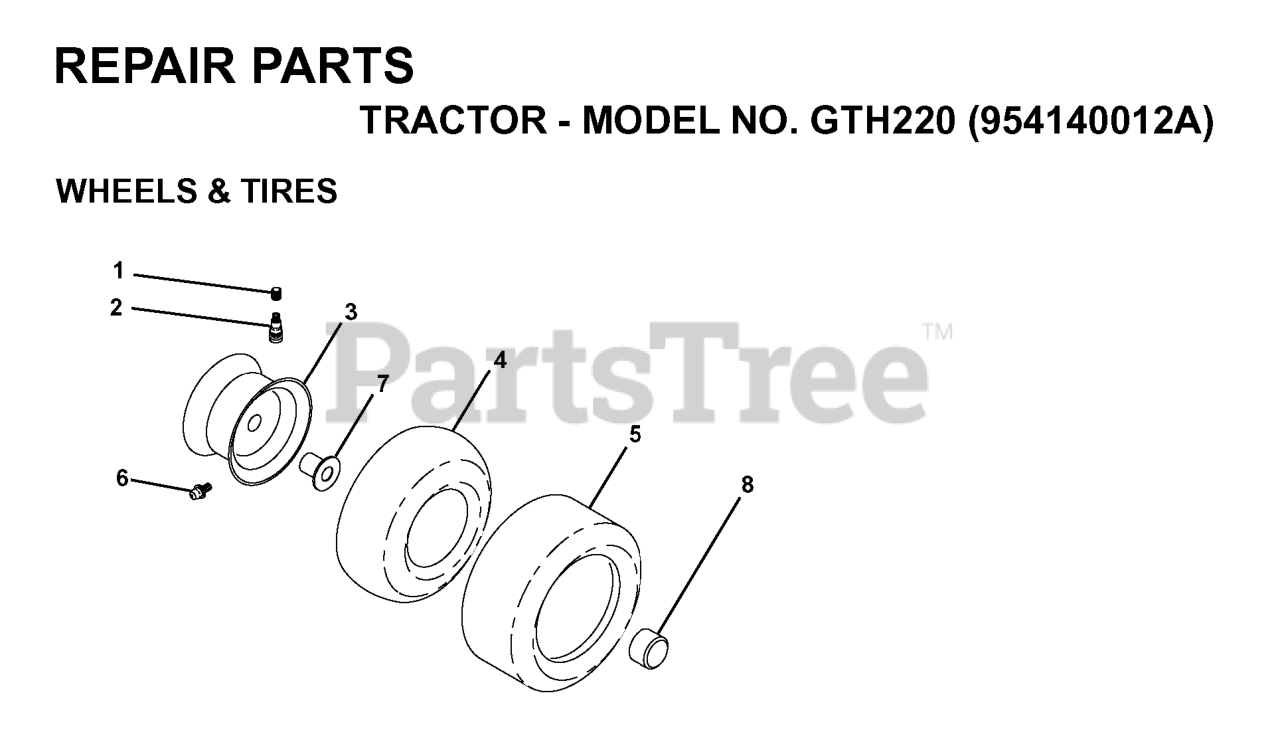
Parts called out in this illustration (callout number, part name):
2	VALVE STEM LT
3	RIM ASSEMBLY, FRONT
4	TUBE.16X6.5/7.5-8
5	TIRE HEAVY DUTY
6	ZERK FITTING M
7	BEARING T
8	CAP.HUB.FRONT.LT.BLACK
